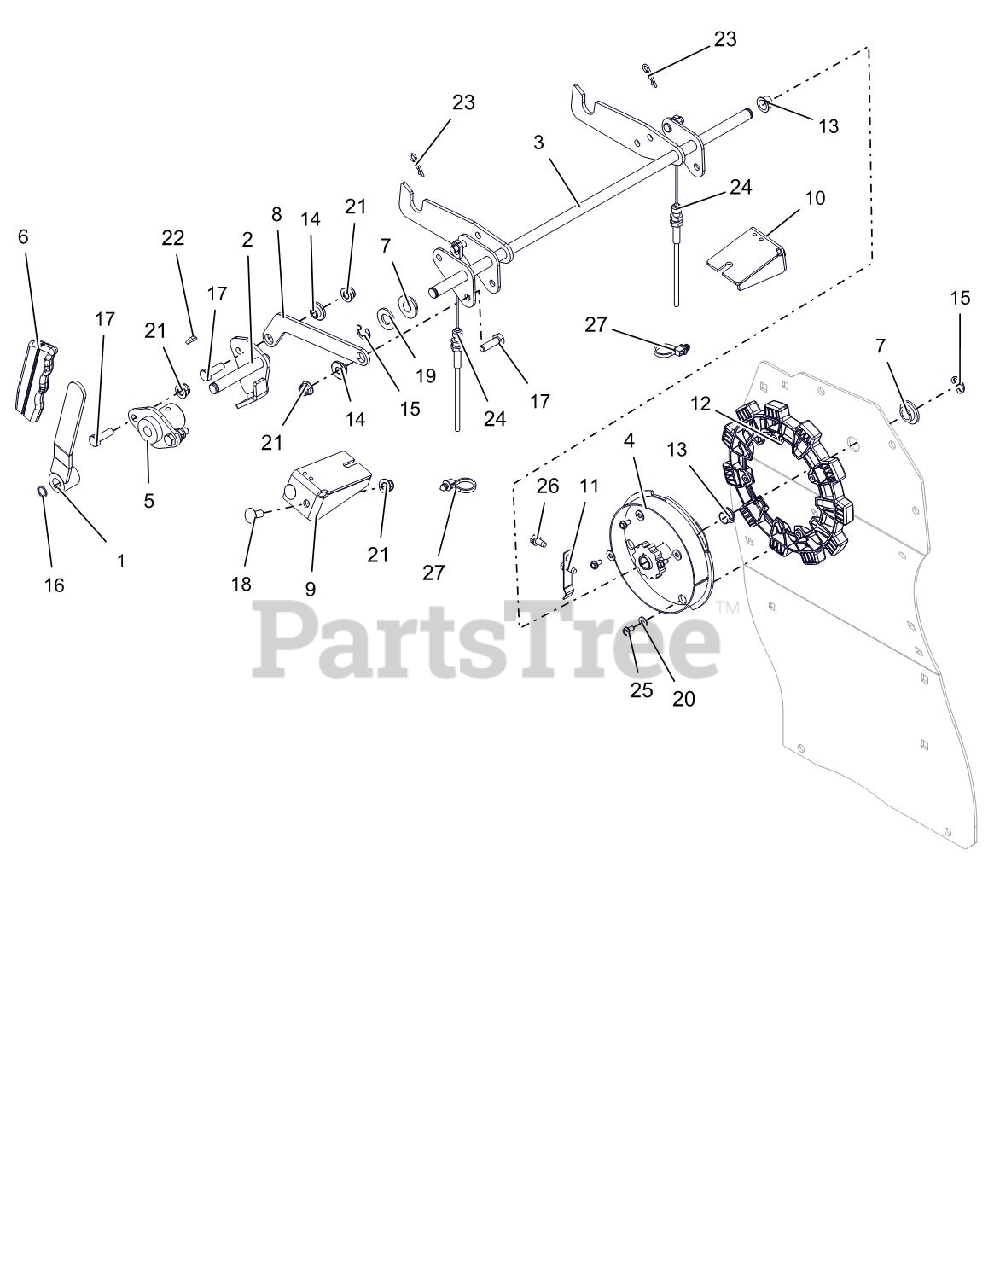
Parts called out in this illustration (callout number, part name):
1	WMT, PARKING BRAKE HANDLE
2	WMT, PARKING BRAKE ACTUATING
3	WLDMT, PS BRAKE INTERLOCK
4	KIT, 36" HOC WLDMT W/DECAL
5	BUSHING, FLANGED
6	GRIP, PARKING BRAKE (YELLOW)
7	BSHG-FLG .515X.750X.310X1.120
8	LINK, BRAKE INTERLOCK
9	BRKT, BRAKE CABLE MTG
10	BRKT, LH CABLE MTG
11	ARM, HOC DETENT
12	WHEEL, HOC
13	BUSHING, POLYLINER-.50 SPLIT
14	BSHG-FLG .32X.500X.344X.880
15	RG-RTNG-EXT .500X.042 (E)
16	RG-RTNG-EXT .500X.050 (SNAP)
17	@BLT-HEX .31-18X1.00 GR5 YWZC
18	@BLT-RDHDSQNK .31-18X.75 G5YZ
19	@WSHR-FL-STL.531X1.06X.095YWZC
20	@WSHR-FL-STL.219X.50X.049 YWZC
21	@NUT-LK-NYL-FLG .31-18 YWZC
22	KEY-WDRF .13X.63 HRD#5
23	PIN-HAIR INT .08X.18X1.18 YWZC
24	CABLE, PROSTANCE P.BRAKE
25	SCR-TAP 10-24X.375 PRE-COAT 80
26	SCR-TAP .25-20X.50 HWH TR YWZ
27	CABLE TIE W/ TREE (.25 HOLE)
